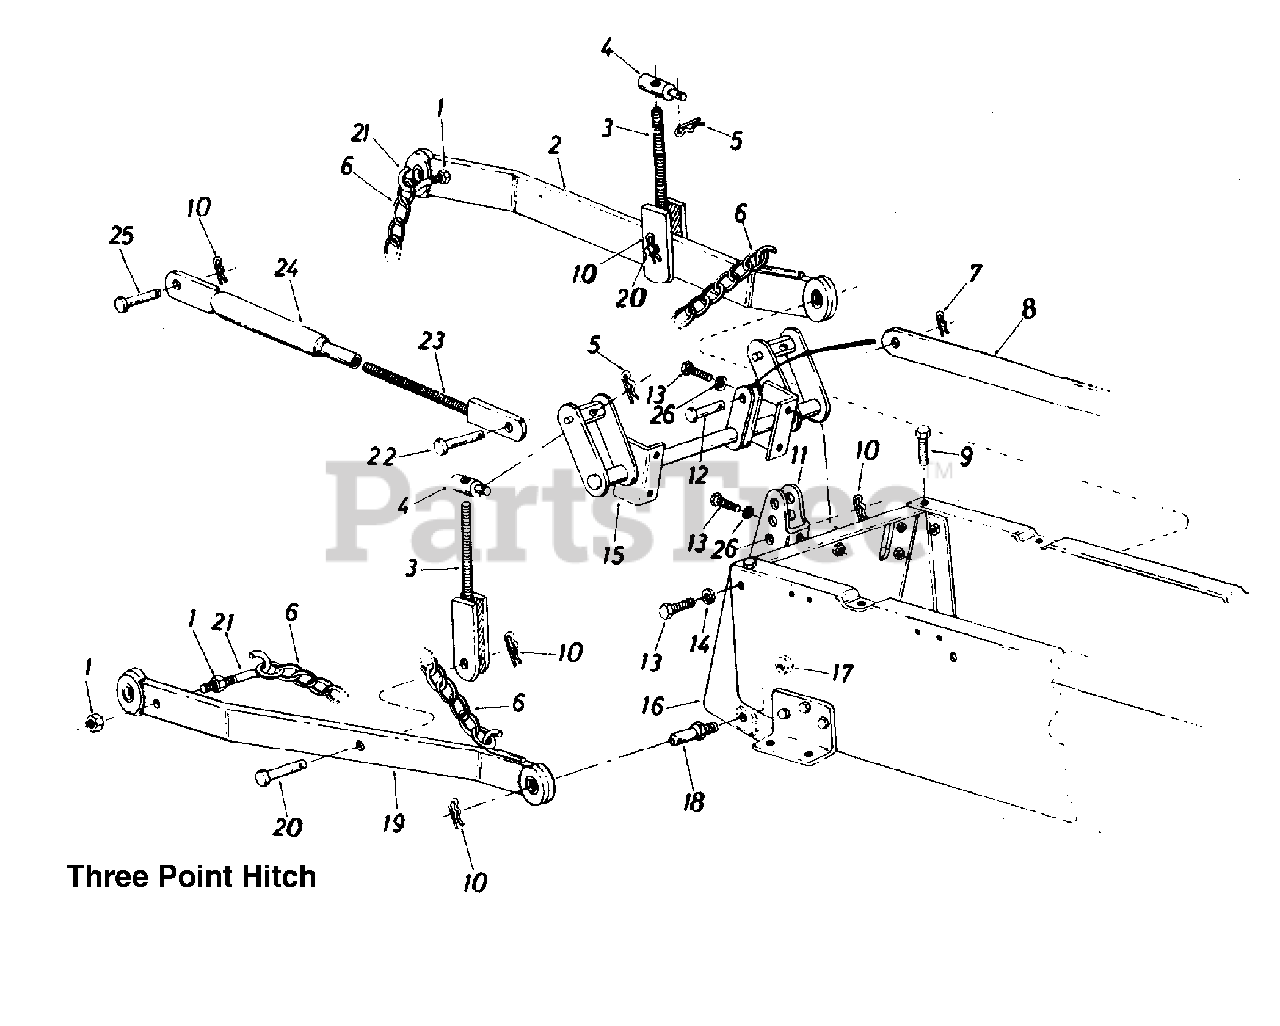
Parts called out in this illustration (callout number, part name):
1	Hex Cent. L-Nut 7/16-14 Thd.
4	Clevis Pin
5	Hitch Pin Clip
6	Chain-20 Links
7	Cotter Pin 1/8" Dia. x 1.25" Lg.
10	Hairpin Cotter
12	Clevis Pin
13	Hex Scr. 3/8-16 x .75" Lg.
14	L-Wash. 3/8" Scr.-H.D.
18	Link Clevis Pin
21	Hitch Chain Hook
22	Clevis Pin .63" Dia. x 2.4" Lg.
23	Clevis Screw
25	Clevis Pin .63" Dia. x 2.4" Lg.
26	L-Wash. 3/8" Scr.-H.D.
13196-0648	PLATE-HITCH - TECH GRAY (0648)
13196-0665	PLATE-HITCH - YARDMAN GREEN (0665)
